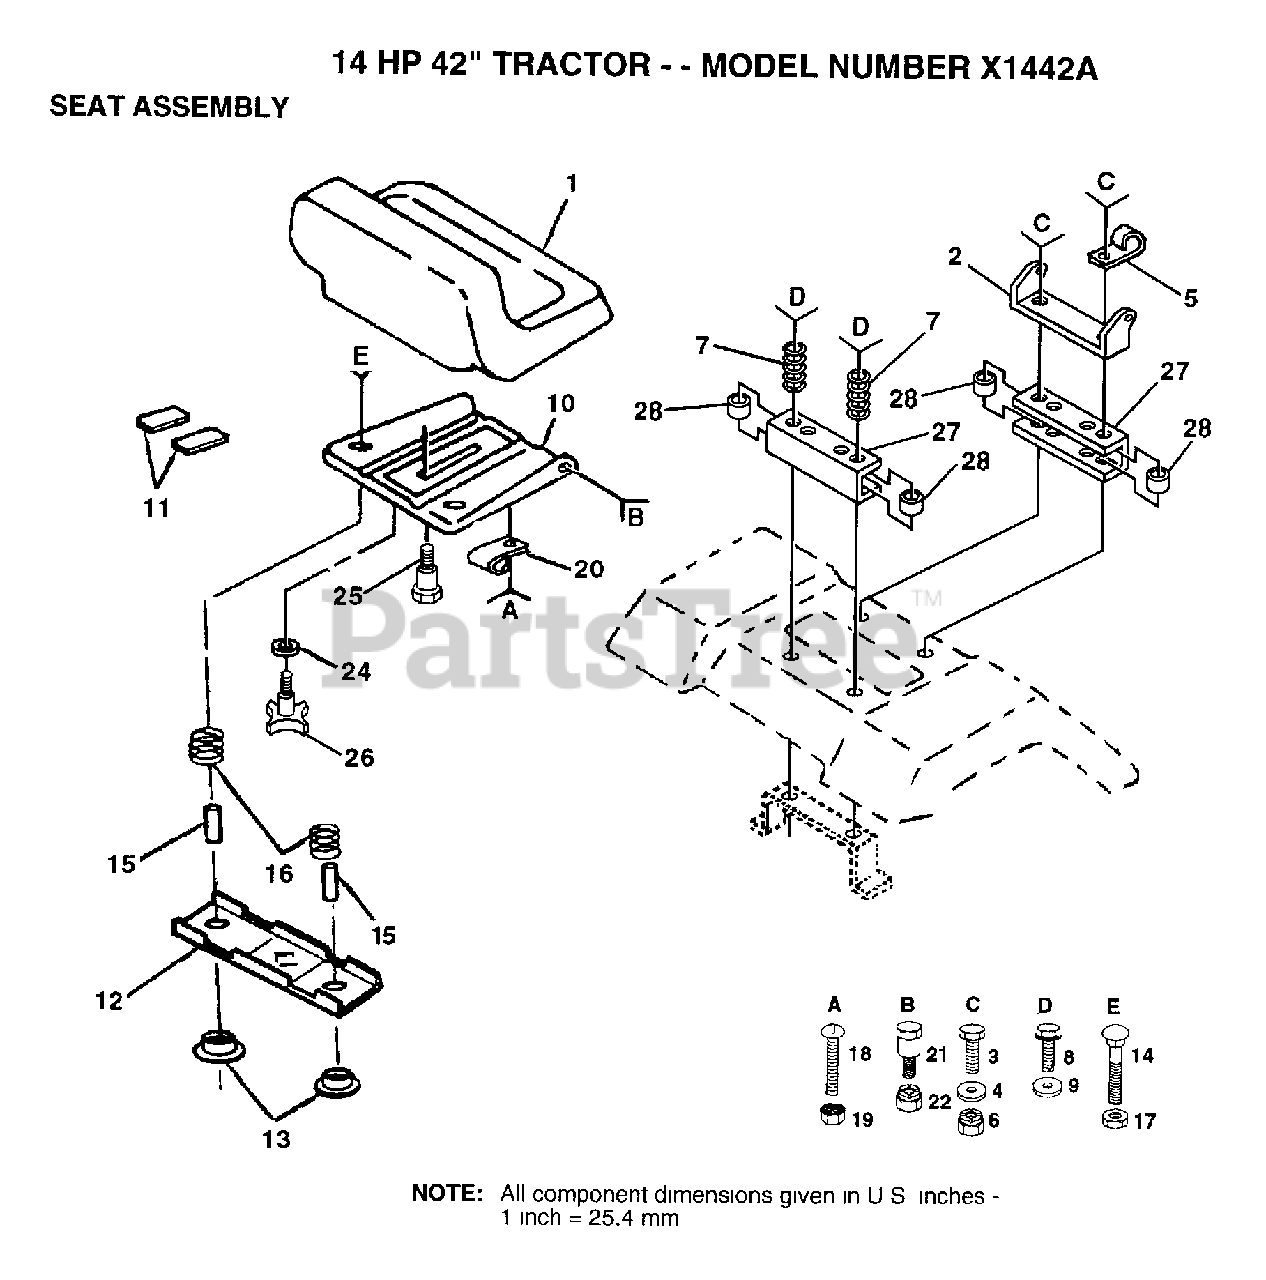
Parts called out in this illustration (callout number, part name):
3	BOLT
4	WASHER PM
5	CLIP T
7	SPRING COMPRESSIO
8	SCREW
9	WASHER
11	STRIP FORM
12	BRKT SWITCH
13	BUSHING
15	SPLIT SPACER
16	SPRING
19	"NUT,KEPS"
24	WASHER
25	"BOLT,SHOULDER"
26	"KNOB 1/2"" YT"
27	SEAT SPACER
28	SPLIT SPACER
